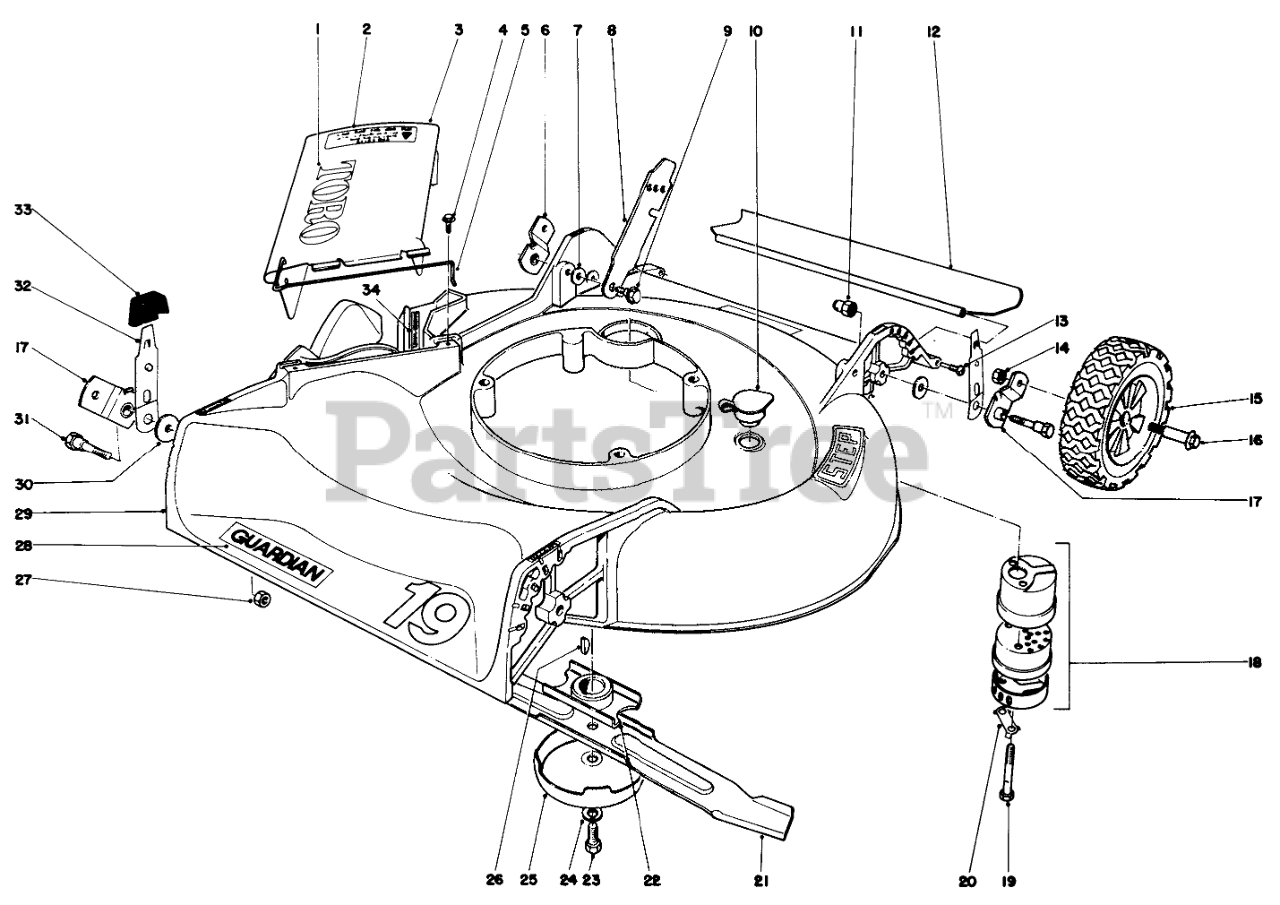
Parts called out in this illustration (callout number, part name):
1	TORO LOGO DECAL
2	Caution Decal
3	Deflector Cover Assembly (Incl. Ref. #1, 2 & 5)
4	SCREW
5	SPRING HINGE
6	Pivot Arm
7	SPACER
8	Latch
9	SCREW-SHOULDER
10	WASHOUT PLUG
11	HANDLE PIVOT NUT
12	SHIELD - TRAILING
13	SAFTEY SHIELD SCREW
14	Nut
15	WHEEL TIRE ASM 8 IN
16	BOLT-WHEEL
17	Pivot Arm
18	Muffler Assembly (Incl. Ref. #19 & 20)
19	SCREW-HH
20	CLIP - LOCKING
21	Blade
22	Blade Retailer
23	SPECIAL SCREW
24	WASHER-LOCK
25	AntiScalp Cup
26	KEY-WOODRUFF
27	Nut
28	Decal
29	Housing 19" (Model #19477)
30	WASHER-PIVOT
31	5/16-18 PIVOT SCREW
32	SPRING ARM ASM
33	KNOB-ARM
34	Decal
